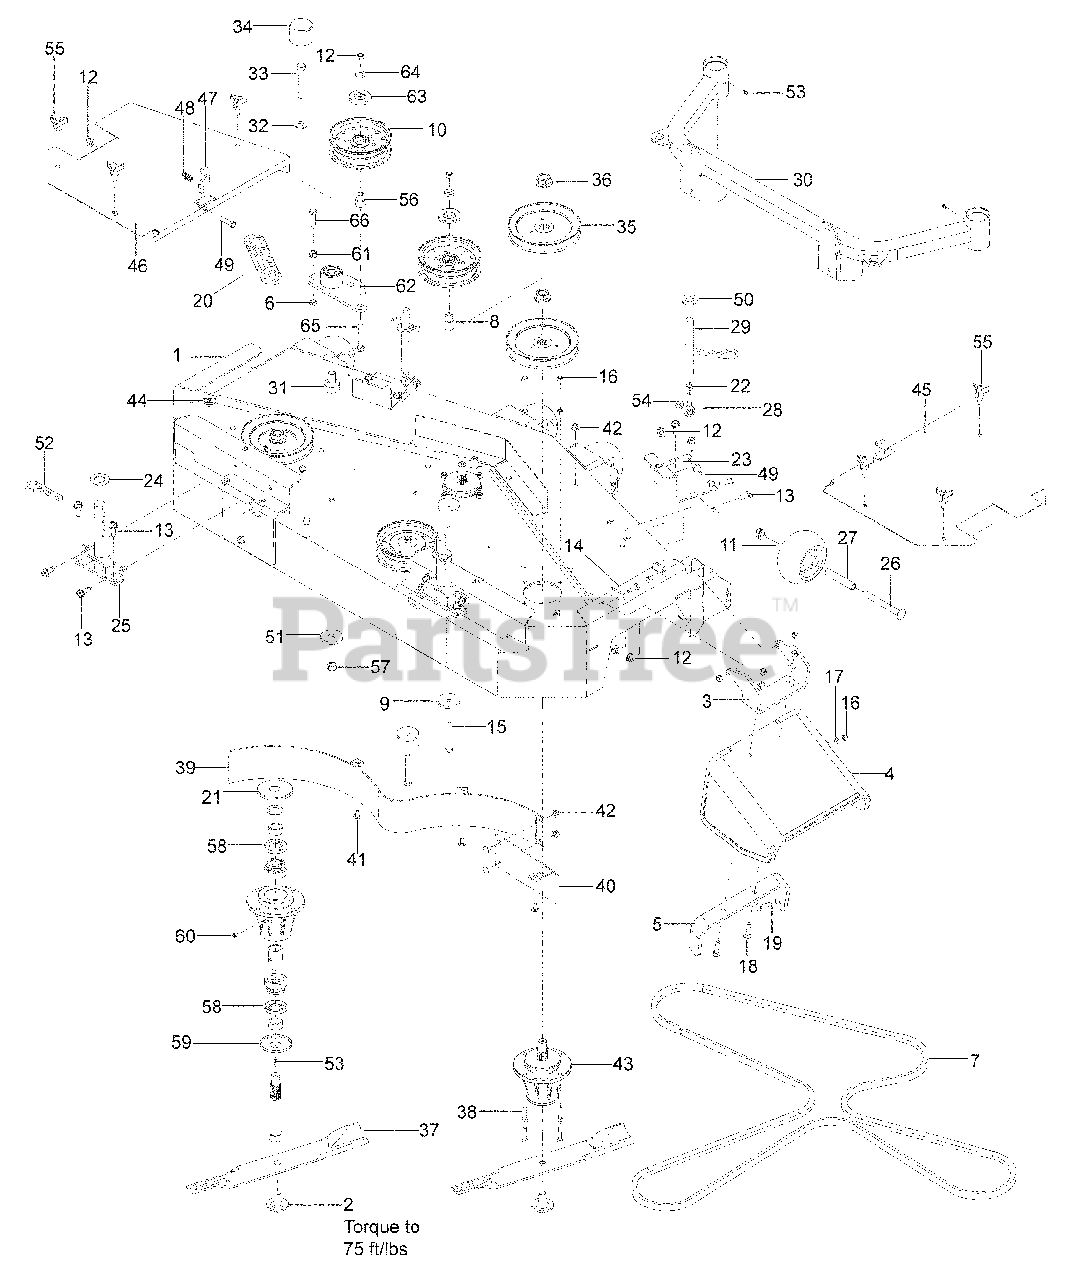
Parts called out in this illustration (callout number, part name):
1	CUTTER DECK w/DECALS
2	BLADE BOLT
3	HINGE, CHUTE
4	CHUTE, RUBBER
5	REINFORCEMENT, BRCKT
6	NUT 3/8-16 HEX JAM
7	BELT, DECK
8	BUSHING, IDLER
9	WASHER, HEAVY
10	PULLEY, IDLER
11	ROLLER, GAUGE
12	NUT 3/8-16 HEX FLG
13	BOLT 3/8-16 x 1 THD FRM
14	HCS 5/16-18 x 1
15	HCS 3/8-16 x 3
16	NUT 5/16-18 HEX NYLOC
17	WASHER 5/16 SAE FLAT
18	RHSNB 5/16-18 x 1½
19	RHSNB 5/16-18 x 1¼
21	SHIELD, DUST
22	NUT 3/8-24 HEX GR 2
23	SUPPORT, FRONT, LH
25	PIN ASSEMBLY
26	RHSNB ½-13 x 4¾
27	TUBE, AXLE
28	ROD END, RH
30	SUPPORT, CASTER
31	PIVOT, BEARING
32	WASHER ½" BELLEVILLE
33	HCS ½-13 x 3¼
34	CAP, VINYL
36	NUT ¾-16 FLANGE
37	BLADE, 18"
38	HCS 5/16-18 x 1¼
39	BAFFLE, MAIN
40	BAFFLE, CENTER
41	RHSNB 5/16-18 x 5/8
42	NUT 5/16-18 HEX FLG NYLOC
43	HOUSING ASM, 72
44	RETAINER, U TYPE
48	SPRING, COMPRESSION
49	HCS 3/8-16 x 1½
50	WASHER ¾ FLAT SAE
51	WASHER, SUPPORT
52	HAIR PIN COTTER
54	WASHER 3/8 x ¾
55	KNOB
56	BUSHING, IDLER
57	NUT ½ HEX NYLOC
58	SHAFT SEAL
59	DUST CAP, BOTTOM
60	POPPET, GREASE
61	NUT 3/8-16 HEX WHIZLK
62	ARM, IDLER w/ BEARINGS
63	SHIELD, DUST
64	WASHER 3/8 THICK
65	RHSNB 3/8-16 x 2¾
66	HCS 3/8-16 x 1½ GR 8
